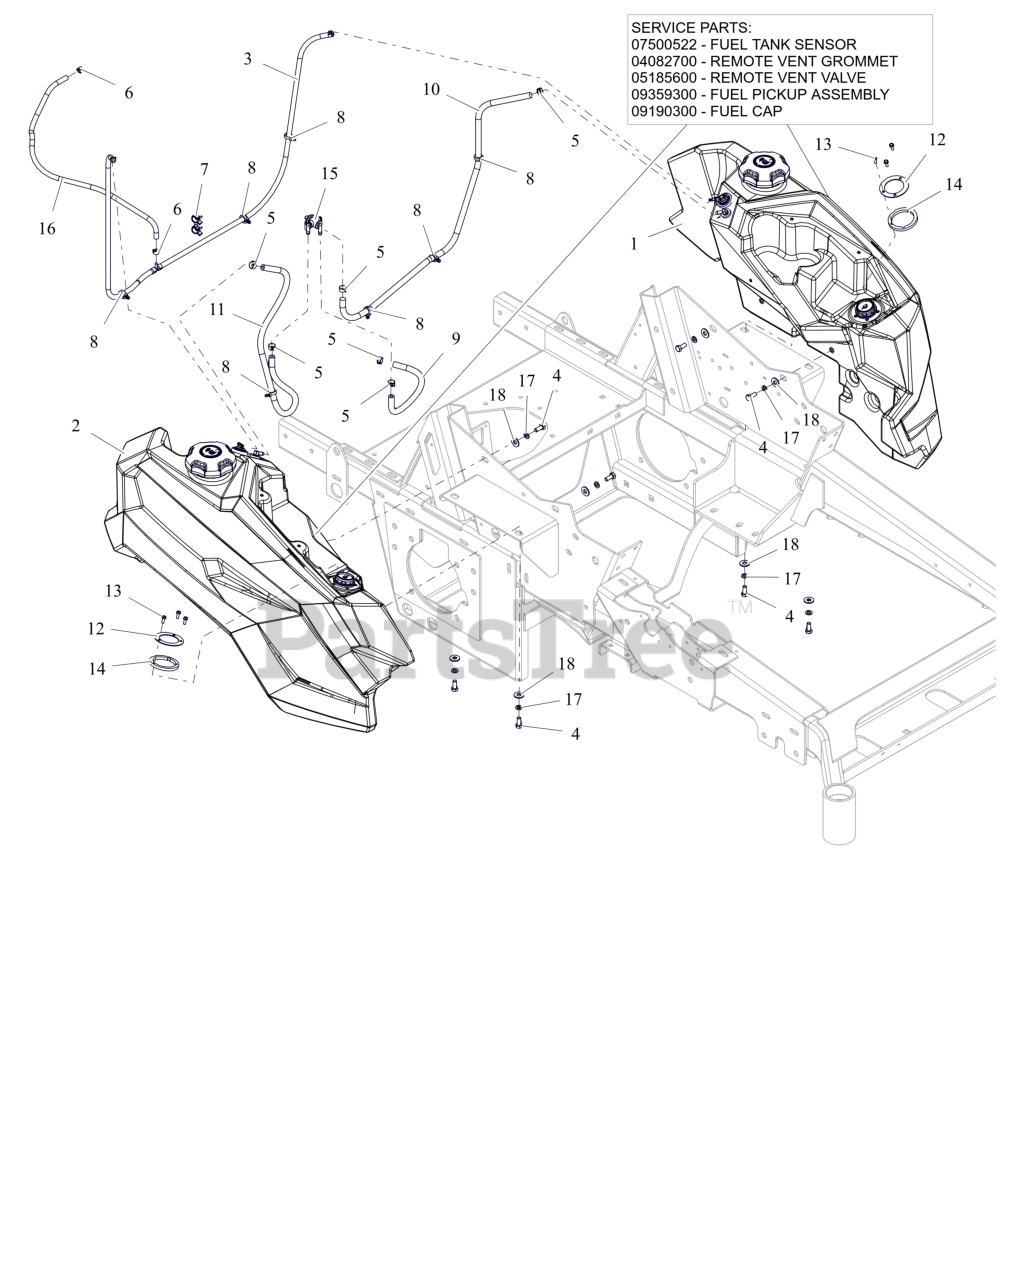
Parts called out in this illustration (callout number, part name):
1	ASM- PT300-500 LH FUEL TANK
1	GAUGE- REMOTE SEALED FUEL
1	GROMMET, REMOTE VENT NITRILE
1	VALVE, COMBINATION VENT 3/16
1	FUEL PICKUP ASSEMBLY
1	CAP, FUEL - 3.50 RATCHET INLET VENT
2	ASM- PT300-500 RH FUEL TANK
3	ASM- PT300/500/600 VENT LINE
4	BLT,HEX .31-18X.75 G5 ZCC
5	CLAMP, FUEL LINE
6	CLAMP-HOSE, SPRING .188
7	CLIP-360DEG SWIVEL.500DIA HOSE
8	CLIP- PUSH-IN X-MAS TREE CABLE
9	1 INCH OF HOSE, .25 LOW-PERM BULK GAS
10	1 INCH OF HOSE, .25 LOW-PERM BULK GAS
11	1 INCH OF HOSE, .25 LOW-PERM BULK GAS
12	RETAINER, FUEL GAUGE (BLACK)
13	SCR-MCH 10-24X.50 HWHSTAINLESS
14	SPCR, FUEL GAUGE RETAINER (BLACK)
15	VALVE, FUEL - WITH MAGNET
16	HOSE, .188 30R7 BULK
17	WSHR,LK-REG .312X.078 ZCC
18	WSHR,FLT .375X.875X.083 ZCC
